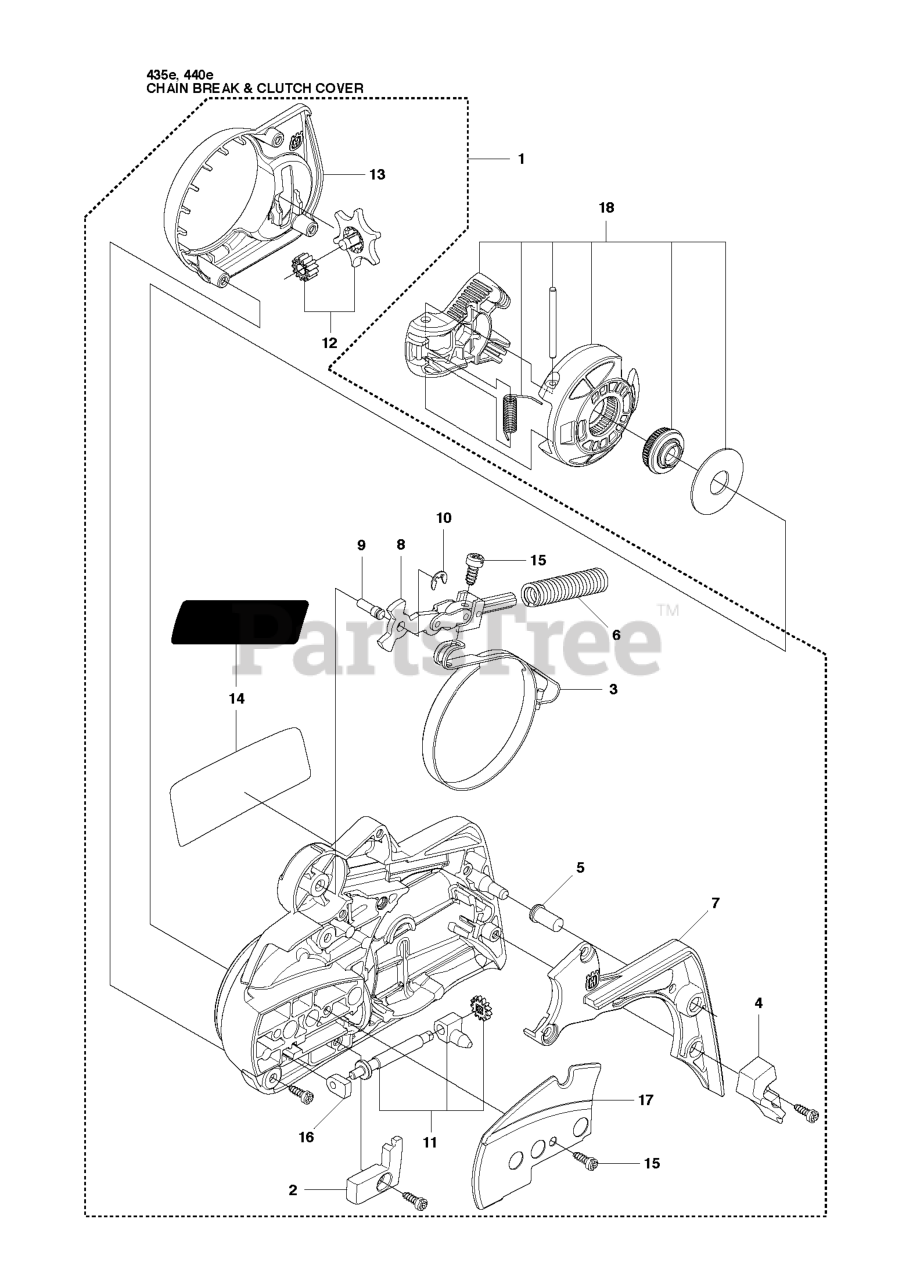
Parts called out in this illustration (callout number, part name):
1	ASSY CHAIN BRAKE HUSQ ORANGE
3	BRAKE BAND ASSY
4	WEAR PROTECTION
6	BRAKE SPRING
11	CHAIN TENSIONER SCREW, COMP.
12	CHAIN TENSIONER WHEEL, COMP.
13	HEAT SHIELD
14	DECAL, CLUTCH HOUSING
16	BEARING SLEEVE
17	WEAR PLATE
18	KNOB, COMPLETE
